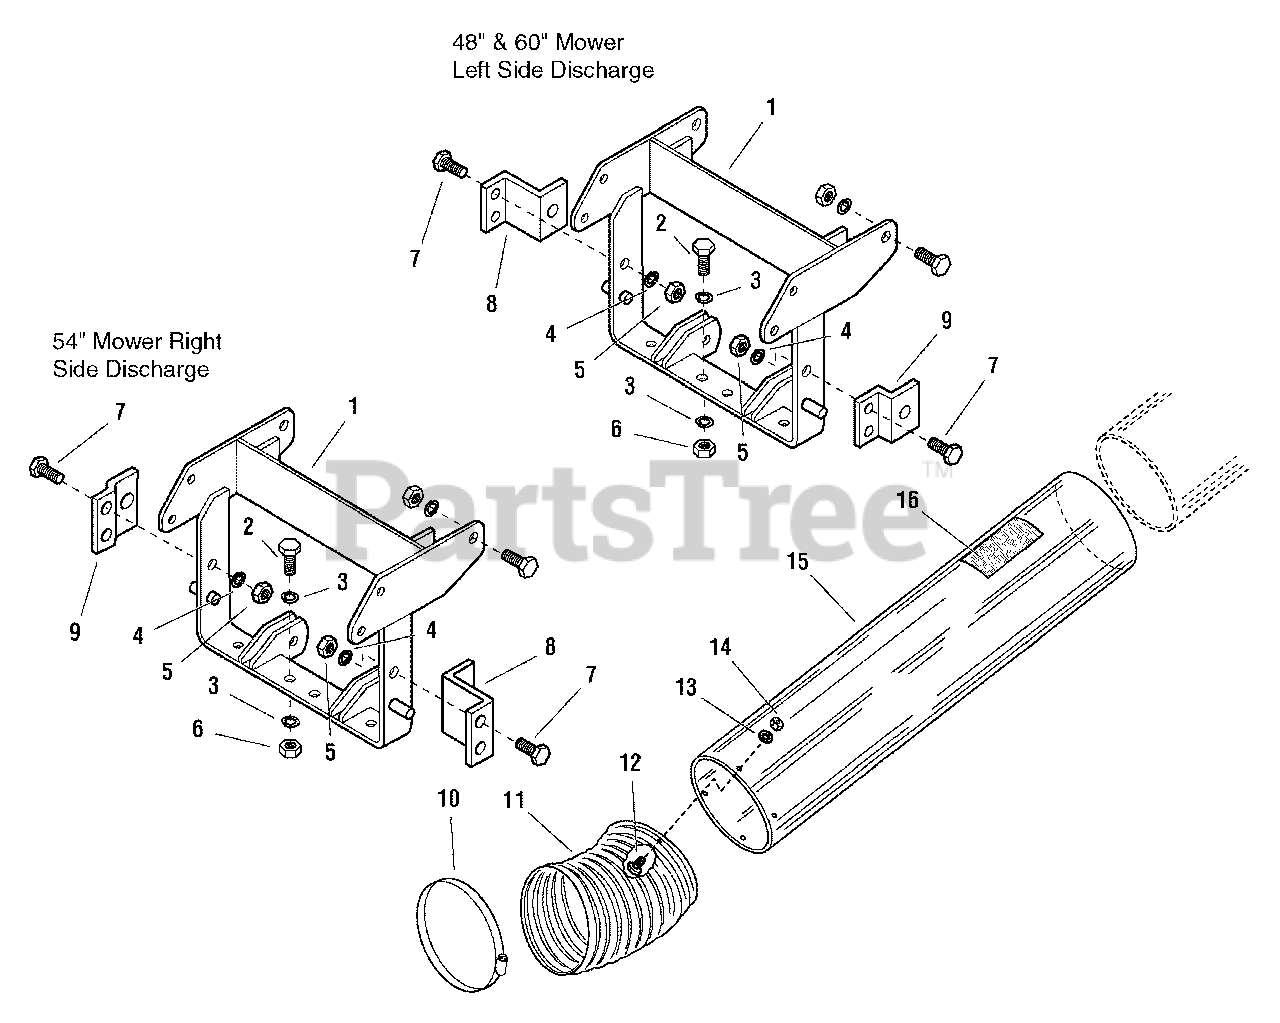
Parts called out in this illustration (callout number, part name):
1	HITCH ASSEMBLY
2	CAPSCREW, Hex, 1/2-13 x 1-1/4
3	LOCKWASHER, 1/2
4	LOCKWASHER, 5/8
5	NUT, 5/8-11
6	NUT, 1/2-13
7	CAPSCREW, 5/8-11 x 1-1/4
8	BRACKET, Long
9	BRACKET, Short
10	CLAMP, Hose 6", Band Type
11	HOSE, Vac Col, 6 x 12
12	SCREW, Truss Head, Phillips, #10-32 x 1/2
13	WASHER, #10-32
14	NUT, Hex Washer, 1/4-20
15	TUBE & DECAL ASSEMBLY (Includes Ref. No.16)
16	DECAL, Cleaning Instructions
